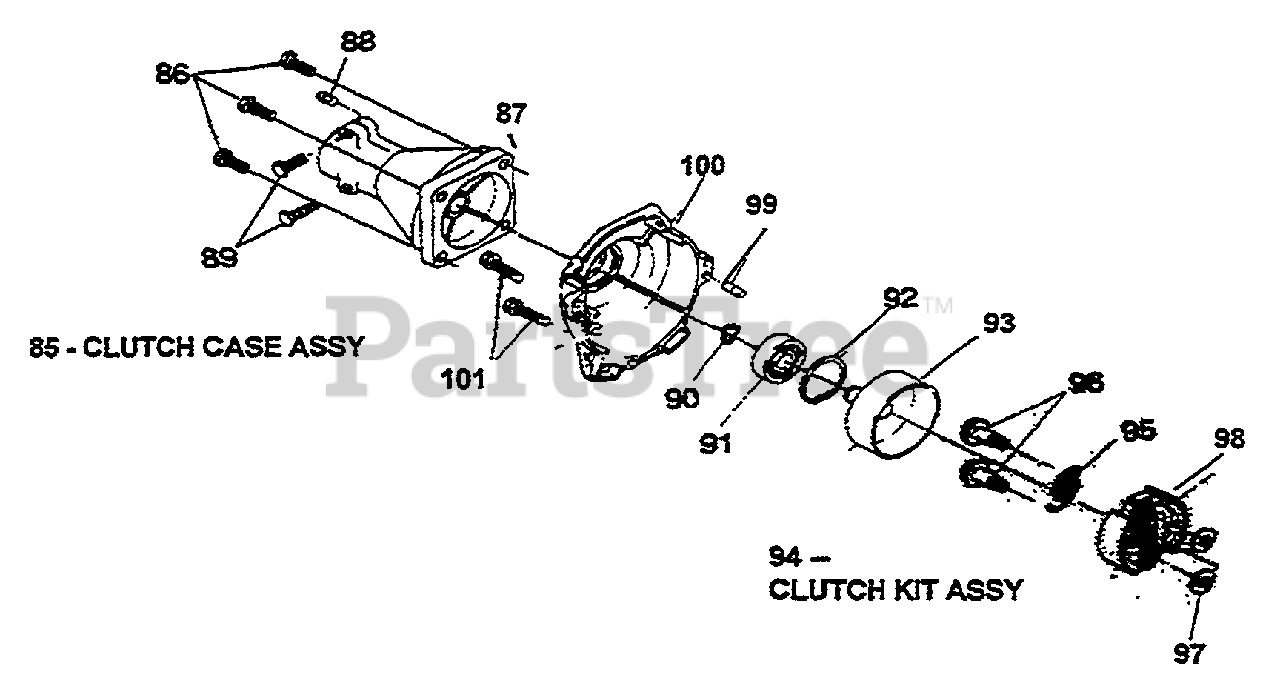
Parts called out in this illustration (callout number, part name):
85	CLUTCH CASE ASSY
86	BOLT & WASHER
87	CASE, CLUTCH
89	BOLT & WASHER
90	SNAP RING
91	BALL BEARING
92	SNAP RING
93	CLUTCH DRUM
94	CLUTCH SHOE ASSY
95	CLUTCH SPRING
98	CLUTCH SHOE
99	DOWEL PIN
100	CASE COVER
